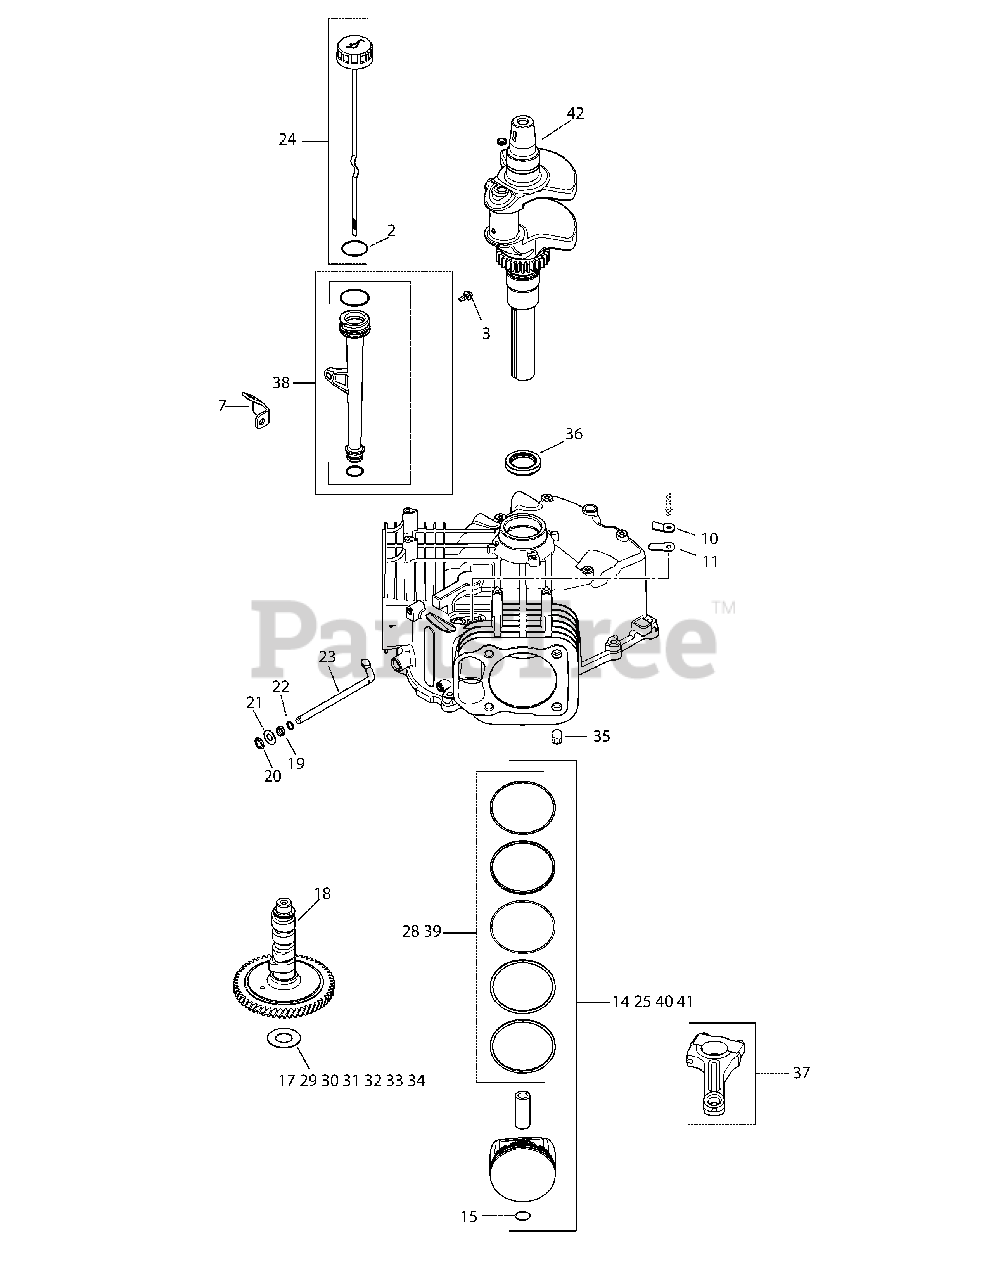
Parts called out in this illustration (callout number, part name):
2	Dipstick Assembly (Includes 2)
3	Flg. Thd. Frm. Screw, M5 X 0.8 X 13
7	Oil Fill Tube Bracket
10	Breather Reed Retainer
11	Breather Reed
14	Piston Kit w/ Ring Set (Inc. 15, 16)
15	Piston Pin Retainer
17	Camshaft Shim (White .028")
18	Camshaft Kit (Inc. KH-25-357-14-S)
19	Governor Cross Shaft Seal
20	Ring Retainer
21	Flat Washer, 9 Mm
22	Flat Washer, 11/32
23	Governor Cross Shaft
24	Dipstick Assembly (Inc. 2)
25	Piston Kit w/ Ring Set (0.25) 83mm
28	Ring Set (.25)
29	Camshaft Shim (Blue .03")
30	Camshaft Shim (Red .032")
31	Camshaft Shim (Yellow .034")
32	Camshaft Shim (Green .036")
33	Camshaft Shim (Gray .038")
34	Camshaft Shim (Black .04")
36	Oil Seal (Helix Lip)
37	Connecting Rod (Std)
38	Tube Assembly (Inc. 4-6)
39	Ring Set (Std)
40	Kit, Piston w/Ring
42	Crankshaft (Includes 2)
